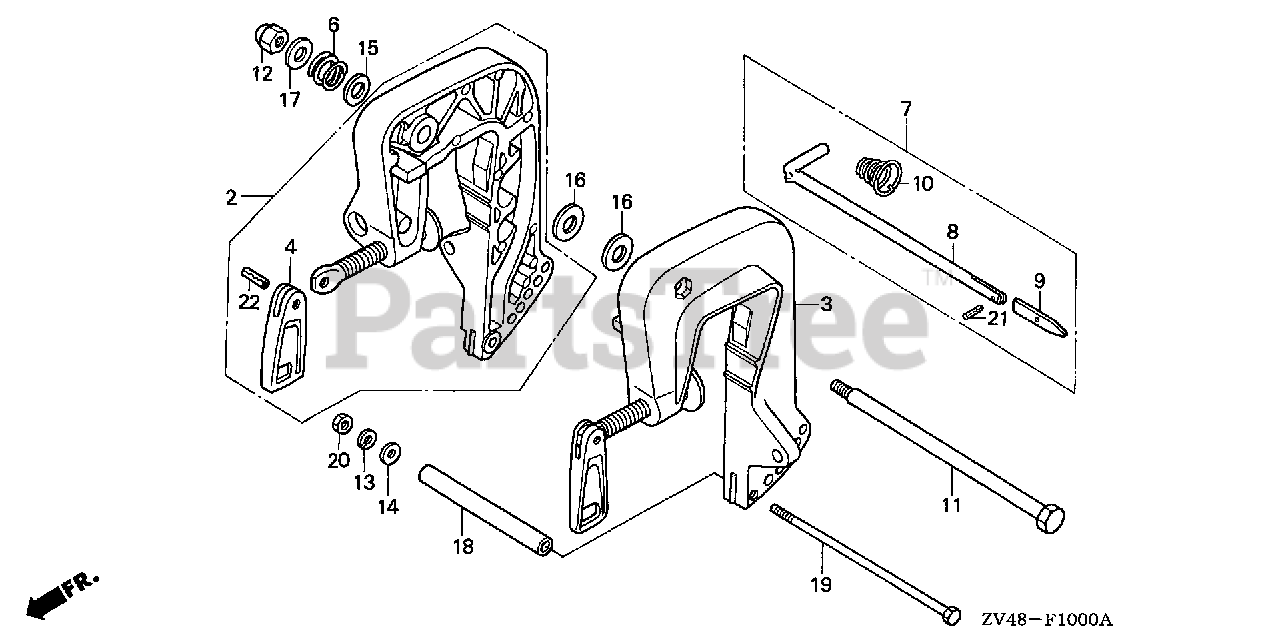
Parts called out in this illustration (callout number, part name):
2	BRACKET, R. STERN *NH282MU* (OYSTER SILVER METALLIC-U)
3	BRACKET, L. STERN *NH282MU* (OYSTER SILVER METALLIC-U)
4	GRIP, CLAMP *NH282MU* (OYSTER SILVER METALLIC-U)
6	SPRING, TILT
7	ROD, ADJUSTING
8	ROD, ADJUSTING
9	STOPPER, ROD
10	SPRING, ADJUSTING ROD
11	BOLT, TILTING
12	NUT, SELF-LOCK (8MM)
13	WASHER, SPRING (6MM)
14	WASHER, PLAIN (6MM)
15	WASHER, PLAIN (10MM)
16	WASHER (10MM)
17	WASHER (8MM)
18	COLLAR, DISTANCE (6MM)
19	BOLT, HEX. (6X160)
20	NUT, HEX. (6MM)
21	PIN, SPRING (2X8)
22	PIN, SPRING (4X14)
